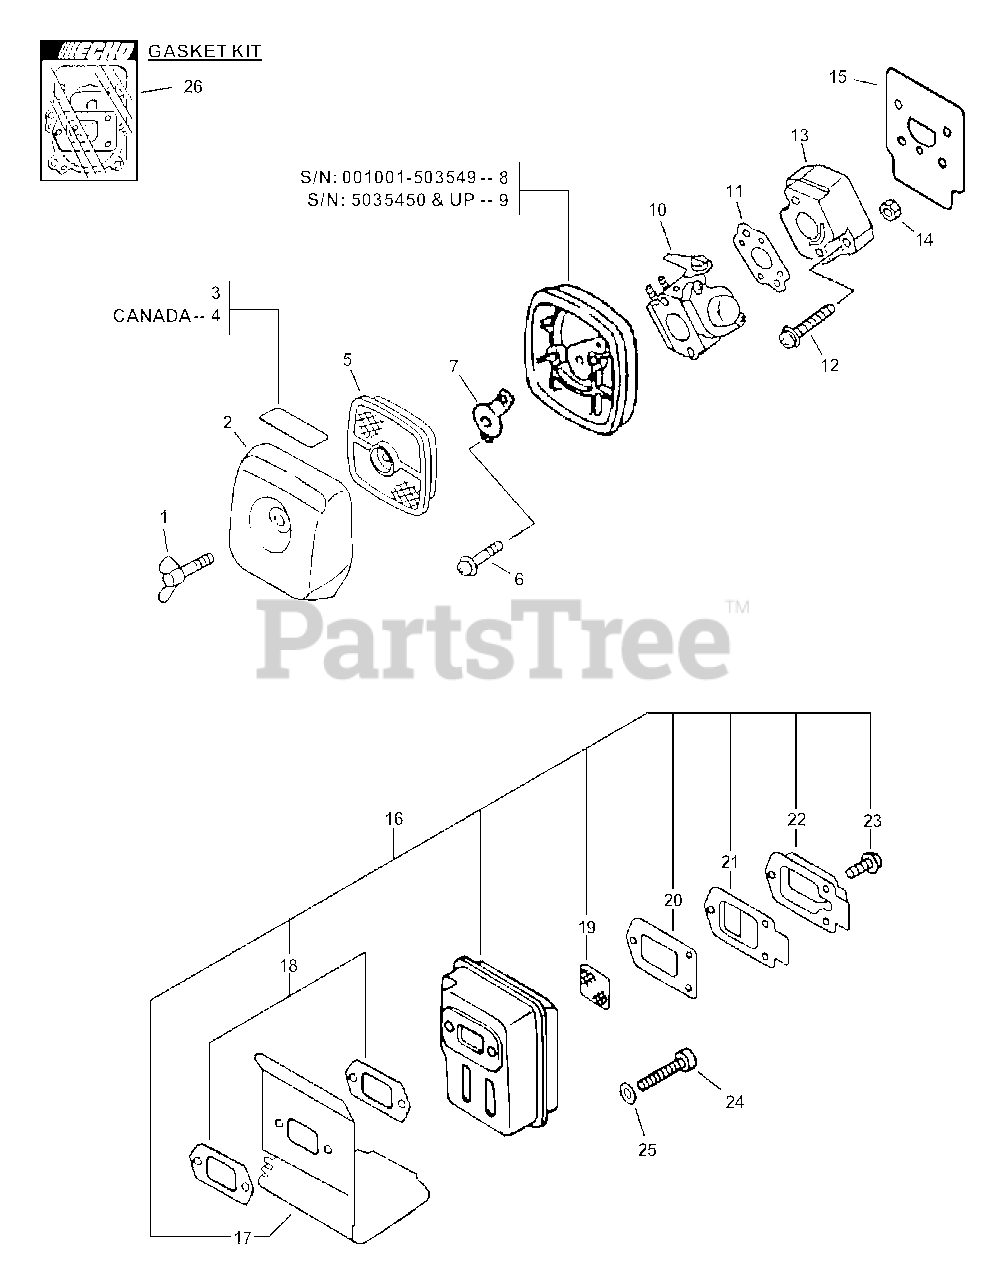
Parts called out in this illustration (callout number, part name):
1	THUMBSCREW
2	COVER, AIR FILTER - BLACK
3	LABEL - CHOKE
4	LABEL - CHOKE
5	FILTER, AIR - SINGLE LAYER
6	SCREW - 5X65
7	PLATE, PREVENT
8	AIR FILTER CASE ASSY
9	CASE, AIR FILTER
10	CARBURETOR C1U-K52
11	GASKET, INTAKE
12	SCREW - 5X20
13	INSULATOR, INTAKE
15	SHIELD, INTAKE
16	MUFFLER ASSY
17	COVER, EXHAUST
18	GASKET, EXHAUST
19	SCREEN, SPARK ARRESTOR
20	GASKET, EXHAUST
21	GASKET, EXHAUST - INNER
22	GUIDE, EXHAUST - OUTER
23	SCREW - 4X10
24	SCREW - 5X55
25	WASHER - 5
26	GASKET KIT
